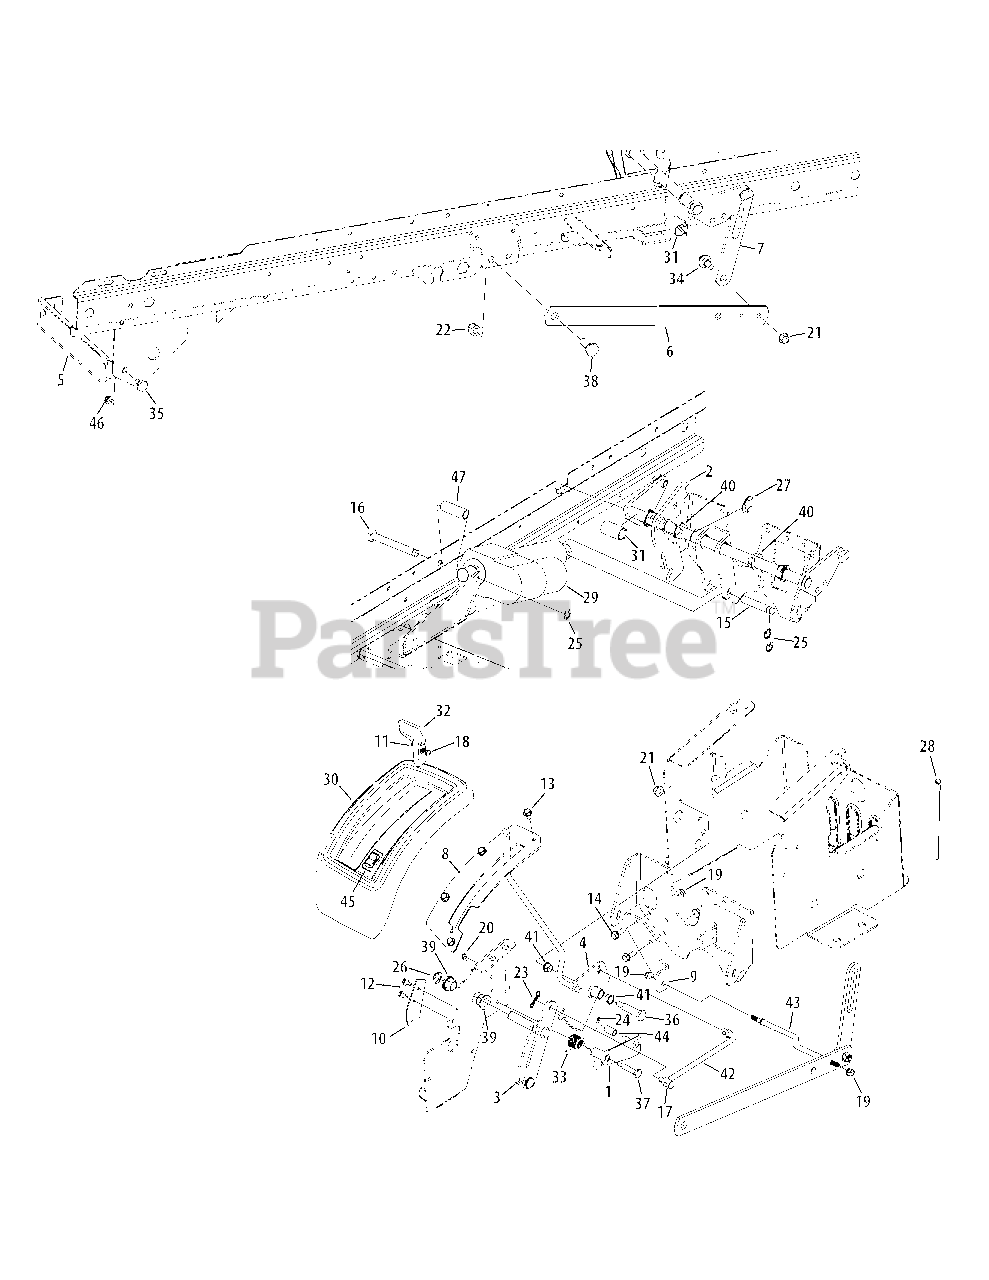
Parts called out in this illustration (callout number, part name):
1	Hub Lift Assembly
2	Electric Shift Assembly
3	Deck Height Adjustment
4	Lift Lever Bracket Assembly
5	Front Hanger Bracket
7	Lift Link Plate
9	Sway Bar Mount Bracket
10	Bearing Stop Plate
11	Machine Screw, #10-24 x .625
12	Hex Washer Screw, 1/4-20 x .500
13	Hex Washer Screw, 5/16-18 x .625
14	Hex Washer Screw, 5/16-18 x .875
15	PIN, .50 x 3.5
16	Clevis Pin, .50 x 4.0
17	Ferrule, 3/8-24 x .375
18	Hex Lock Nut, #10-24
19	Flange Lock Nut, 5/16-18
20	Flange Lock Nut, 1/4-20
21	Flange Lock Nut, 3/8-16
22	Hex Lock Nut, 1/2-13
23	Bow-Tie Cotter Pin, 72
24	Cotter Pin, .125 x .75
25	E-Ring, .500
26	E-Ring, .625
27	E-Ring, .875
28	Cable Tie, 3/16 x .05 x 7.4
29	Plow Lift Actuator
30	Lift Cover
32	Electric Lift Knob
33	Torsion Spring
34	Shoulder Screw, 1/2 x .29
35	Shoulder Screw, 3/8-16 x .562 x .360
36	Shoulder Screw, .498 x 1.635
37	Shoulder Screw, .374 x 1.375
38	Shoulder Screw, 1/2-13 x .625 x .36
39	Hex Flange Bearing
40	Hex Flange Bearing, .78
41	Flange Bearing, .500 x .34
42	Electric Lift Rod Adjuster
43	Anti-Sway Deck Rod
44	Spacer, .35 x .5 x .851
45	Plow Lift Switch
46	Jam Lock Nut, 3/8-16
47	Spacer, .55 ID x .75 OD x 2.06
